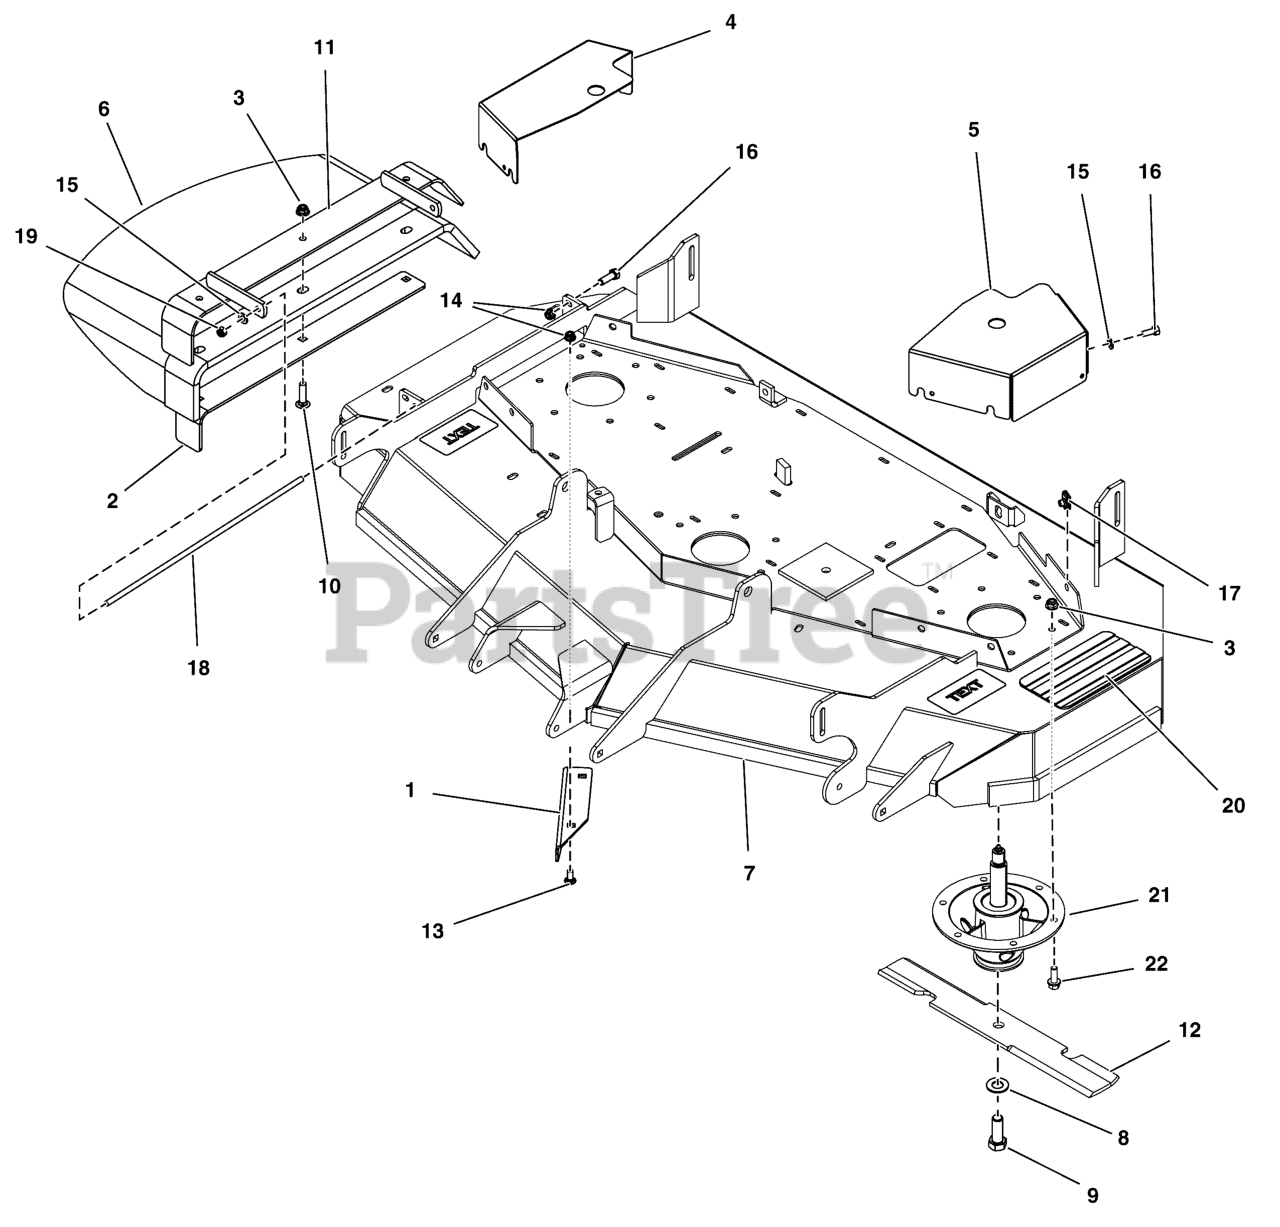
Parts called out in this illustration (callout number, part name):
1	DEFLECTOR
2	SUPPORT, DISCHARGE CHUTE - BLK
3	NUT, 3/8 - 16 HEX NYLOCK FLANGE
4	GUARD, 52 DECK, RH - RED
5	GUARD, 52 DECK, LH - RED
6	CHUTE, RUBBER DISCHARGE (5104442)
7	DECK SHELL W/ DECALS, 2100-52 (5422057B)
7	DECK SHELL W/DECALS, 2100-52E (5422057B)
8	WASHER, BLADE BOLT, 9/16" F436, CZ
9	BOLT, 5/8-11 X 1-3/4 GD8
10	BOLT, 3/8-16 X 1-1/2, CARRIAGE, GD5, CZ
11	WELD, MOUNT, DISCHARGE CHUTE - BLK
12	BLADE, 18 X .25 X 2.5, 1 X 3.5 (SET OF THREE)
13	BOLT, 5/16-18 X 3/4, CARRIAGE, GD5, CZ
14	NUT, 5/16-18 HEX NYLOCK FLANGE NUT
15	WASHER, 5/16" SAE
16	BOLT, 5/16-18 X 3/4 GD5
17	BODY CLIP, 5/16-18-7GA MATERIAL
18	ROD, MOUNT, CHUTE, 61, CZ
19	NUT, 5/16-24 HEX NYLON LOCK
20	SAFETY WALK, 4.00 X 7.50
21	SPINDLE ASSM, CAST IRON 8.0-6 BOLT, LS
22	BOLT, 3/8-16 X 1, FLANGE, GD 5, CZ
